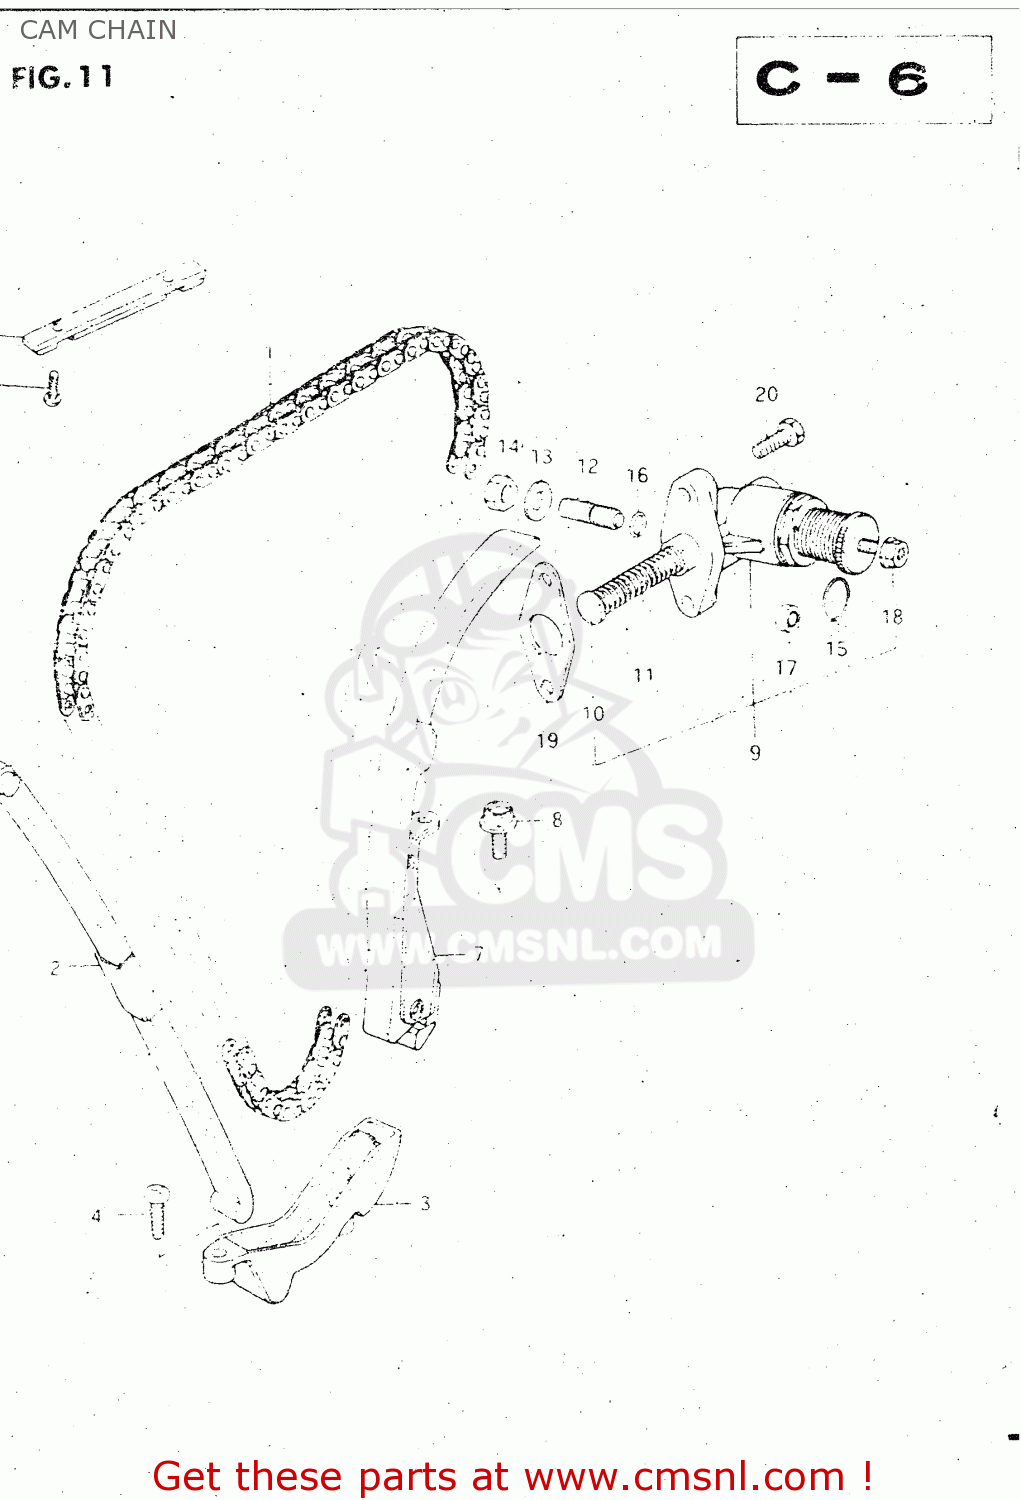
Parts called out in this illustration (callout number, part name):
1	CHAIN,CAMSHAFT DRIVE
2	GUIDE,CAM CHAIN NO.1
3	HOLDER,CAM CHAIN GUIDE
4	SCREW
5	GUIDE,CAM CHAIN NO.3
6	SCREW
7	TENSIONER,CAM CHAIN
8	BOLT
9	ADJUSTER,CAM CHAIN TENSIONER
10	ROD,PUSH
11	SPRING
12	SCREW
13	WASHER
14	NUT
15	O RING(D:2.4,ID:20.8)
16	O RING(D:1.9,ID:5.7)
17	SEAL,OIL(10X16X4)
18	NUT
19	GASKET,TENSIONER ADJUSTER (MCA)
20	SCREW (6X25)
